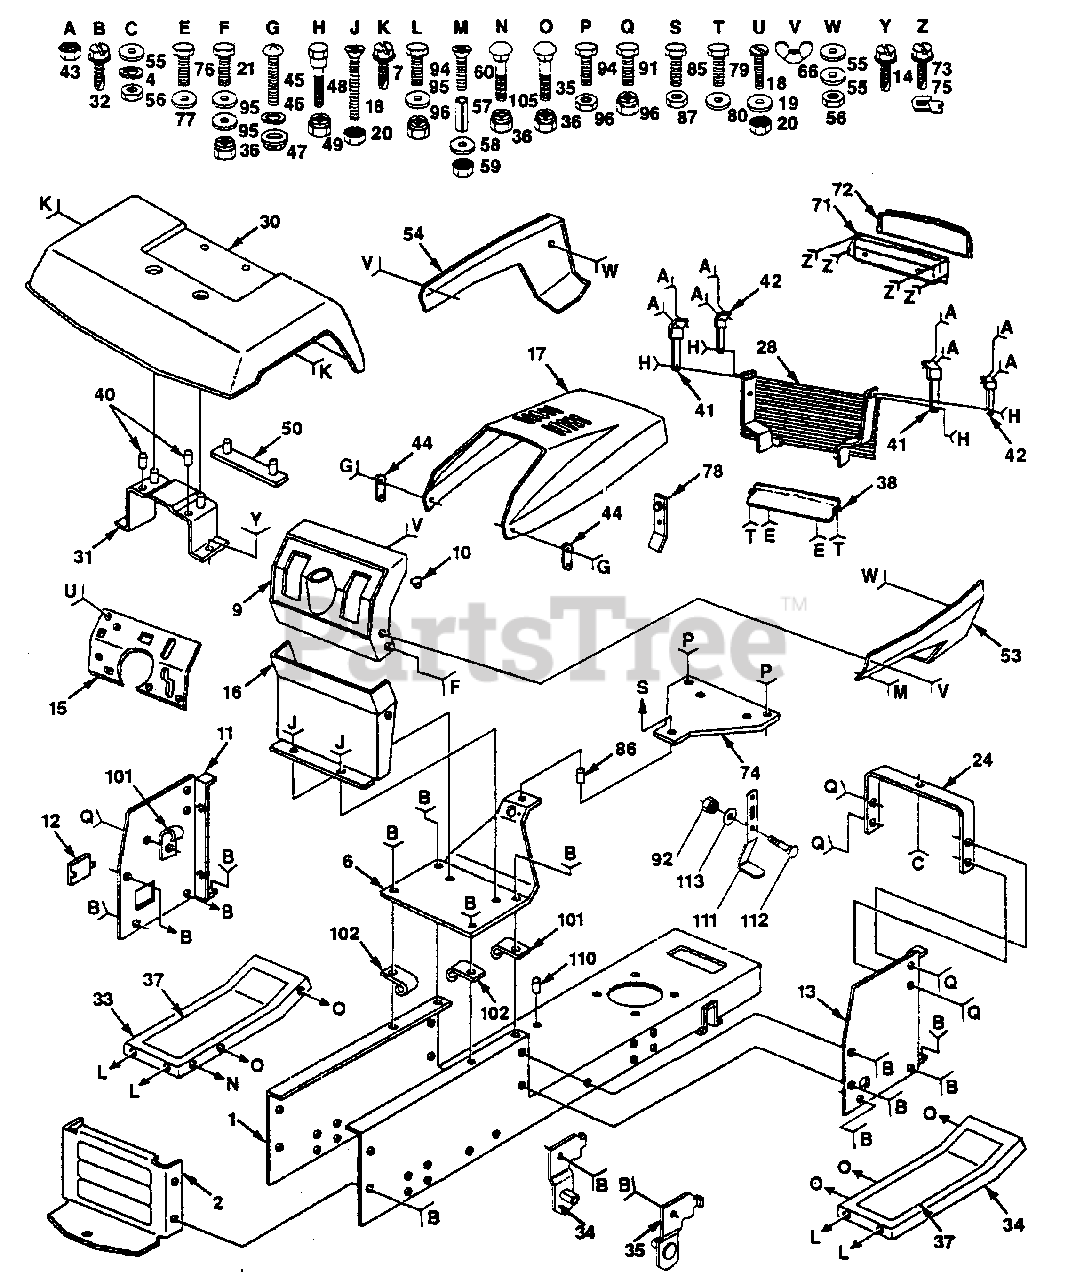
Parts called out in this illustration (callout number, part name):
1	Chassis
2	Drawbar
4	Washer, Lock, Hvy Hlcl 1/4
7	Screw Thdrol 3/8-16 x 1/2 Ty-tt
10	Plug, Button
11	Dash Panel, LH
12	Cover Access
13	Dash Panel, RH
14	Screw Thdrol 3/8-16 3/4 Ty tt
18	Screw, Machine 5/16-18 UNC x 3/4
19	Washer 11/32 x 11/16 x 16 Gauge
20	Nut, Hex, Keps 5/16-18 UNC
21	Bolt, Hex, Fin. 3/8-16 x 1
24	Support, Dash
31	Bracket Fender
32	Screw, Thd., Roll. 3/8-16 x 3/4
35	Bolt, Carriage 3/8-16 x 3/4
36	Nut Lock Hex W/Ins 3/8-16 UNC
37	Pad, Footrest
38	Strap Pnt Grille
40	Nut, Push, Nylon
41	Strap Assembly, Hinge, Rear
42	Strap Assembly, Hinge, Front
43	Nut, Hex, Keps 1/4-20 UNC
45	Screw, Machine, Cross Pan Head #10-24 x 1/2
46	Washer, Lock #10
47	Nut, Weld
48	Bolt, Shoulder 1/4-20 UNC
49	Nut, Crownlock 1/4-20 UNC
50	Strap, Fender
53	Side Panel, RH
54	Side Panel, LH
55	Washer 9/32 x 3/4 x 16 Gauge
56	Nut, Hex, Fin. 1/4-20 UNC
57	Spacer, Split #10 x 3/4
58	Washer 7/32 x 1/2 x 18 Gauge
59	Nut, Hex, Keps #10-24 UNC
60	Screw, Machine, Cross Pan Head #10-24 x 1-1/4
66	Wing Nut, Plastic 1/4-20
71	Bezel Asm.
72	Lens Headlight Bar Clear
73	Screw Hex Whd Tap #10-16 x 5/8
74	Plate, Battery Support
75	Fastener "j" (Use #10 Screw)
76	Screw Thdrol 5/16-18 x 3/4 TyT
77	Washer 13/32 x 3/4 x 10 Ga.
78	Bracket Grille Galv
79	Screw Hex Wsh 1/4-20 UNCx 3/4
80	Washer 9/32 x 5/8 x 16 Ga.
85	Bolt, Hex, Fin. 5/16-18 UNC x 2
86	Spacer, Split
87	Nut,Lock, Hex w/Ins. 5/16-18
92	Nut Lock 3/8
94	Bolt, Hex, Fin. 3/8-16 UNC x 3/4
95	Washer 13/32 x 13/16 x 12 Gauge
96	Nut, Crownlock 3/8-16 UNC
101	Clip, Insulator
102	Clip, Fuel Line
103	Pivot Bracket Assembly, Rear, LH
104	Pivot Bracket Assembly, Rear, RH
105	Bolt, Carriage 3/8-16 UNC x 1
110	Bushing Snap Split
111	Stop Over Center 44" 20/23" T
112	Bolt Carr 3/8-16 x 1.00
113	Washer 13/32 x 1 x 12 Ga.
